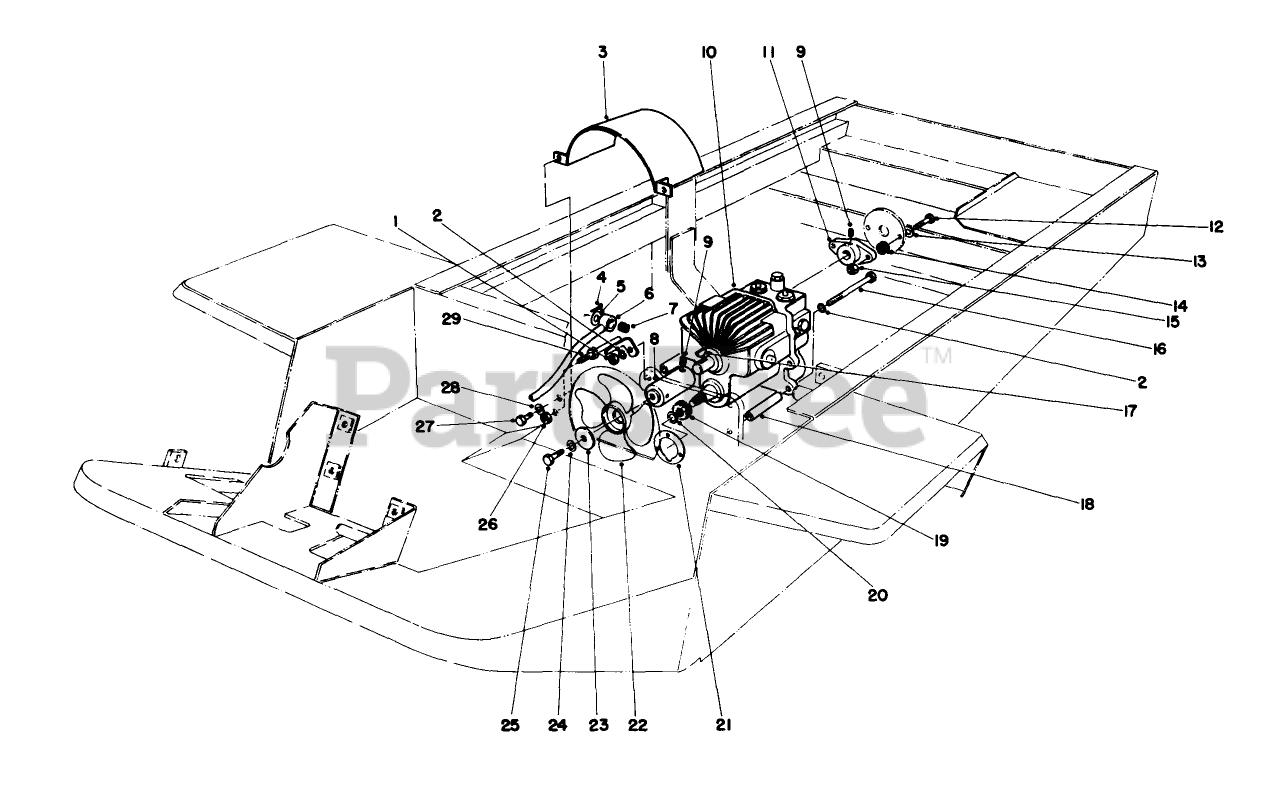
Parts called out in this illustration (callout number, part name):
1	NUT-HEX
2	WASHER-LOCK
3	Fan Shroud
4	PIN-COTTER
5	WASHER-FLAT
6	PUMP CONTROL TUBE WA
7	BUSHING-RUBBER
8	Hub & Plug
9	SCREW-SET, HSH
10	Transmission
11	HUB-PUMP
12	SCREW-HH
13	WASHER-FLAT
14	SPACER-RUBBER COUPLNG
15	NUT-HEX
16	SCREW-HH
17	KEY-WOODRUFF
18	SPACER-MOUNTING
19	Gear
20	Ring-Snap
21	GASKET-TRANSMISSION
23	WASHER
24	WASHER-LOCK
25	SCREW-HH
26	NUT-JAM
27	SCREW-HH
28	WASHER-LOCK
29	Axle Support
